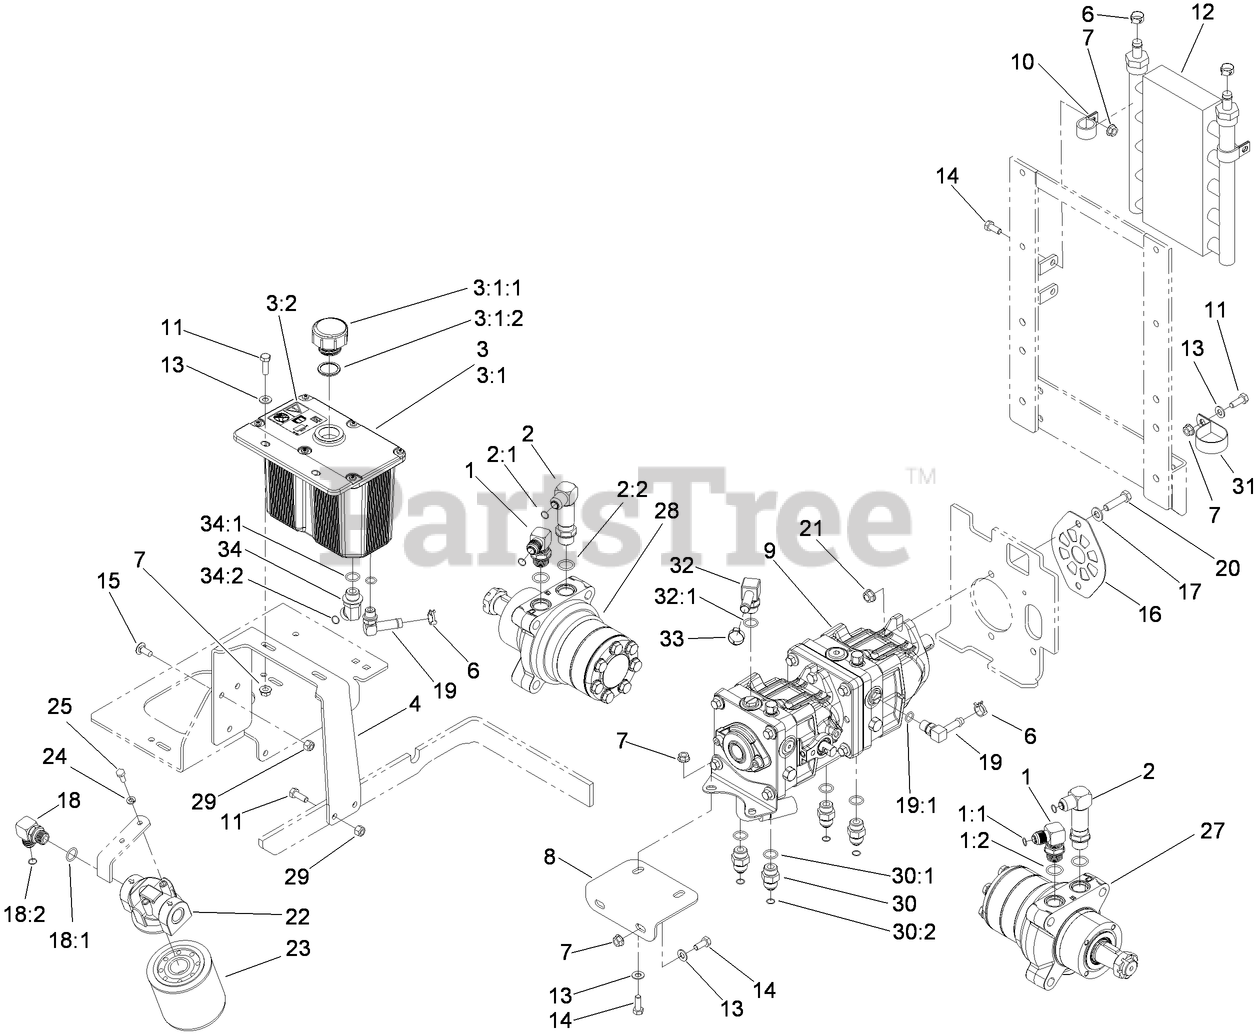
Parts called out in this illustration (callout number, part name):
1	FITTING-HYD, 90 DEG
1:1	O-Ring
1:2	O-RING
2	FITTING-ELBOW-90
2:1	O-Ring
2:2	O-RING
3	HYDRAULIC TANK ASM
3:1	TANK-HYDRAULIC
3:1:1	CAP-RESERVOIR, HYD
3:1:2	GASKET-CAP
3:2	DECAL-WARNING
4	BRACKET-TANK, HYDRAULIC
6	CLAMP-HOSE
7	NUT-HF
8	BRACKET-PUMP, FRONT
9	TANDEM PUMP ASM
10	R-CLAMP
11	SCREW-HH
12	COOLER-OIL, HYDRO
13	WASHER-PLAIN
14	SCREW-HH
15	SCREW-CARR
16	PLATE-SHIELD, PUMP
17	WASHER-FLAT
18	FITTING-90 DEG
18:1	O-RING
18:2	O-Ring
19	FITTING-ELBOW, 90
19:1	O-RING
20	SCREW-HH
21	NUT-HHF, WHIZ
22	HEAD-FILTER
23	CARTRIDGE-FILTER, OIL
24	WASHER-LOCK
25	SCREW-HH
27	HYD MOTOR ASM (CCW)
28	HYD MOTOR ASM (CW)
29	NUT-LOCK, NI
30	FITTING-STRAIGHT
30:1	O-RING
30:2	O-Ring
31	CLAMP-R
32	FITTING-ELBOW, 90 DEG
32:1	O-RING
33	CLAMP-HOSE
34	FITTING-HYD, 45 DEG
34:1	O-RING
34:2	O-Ring
